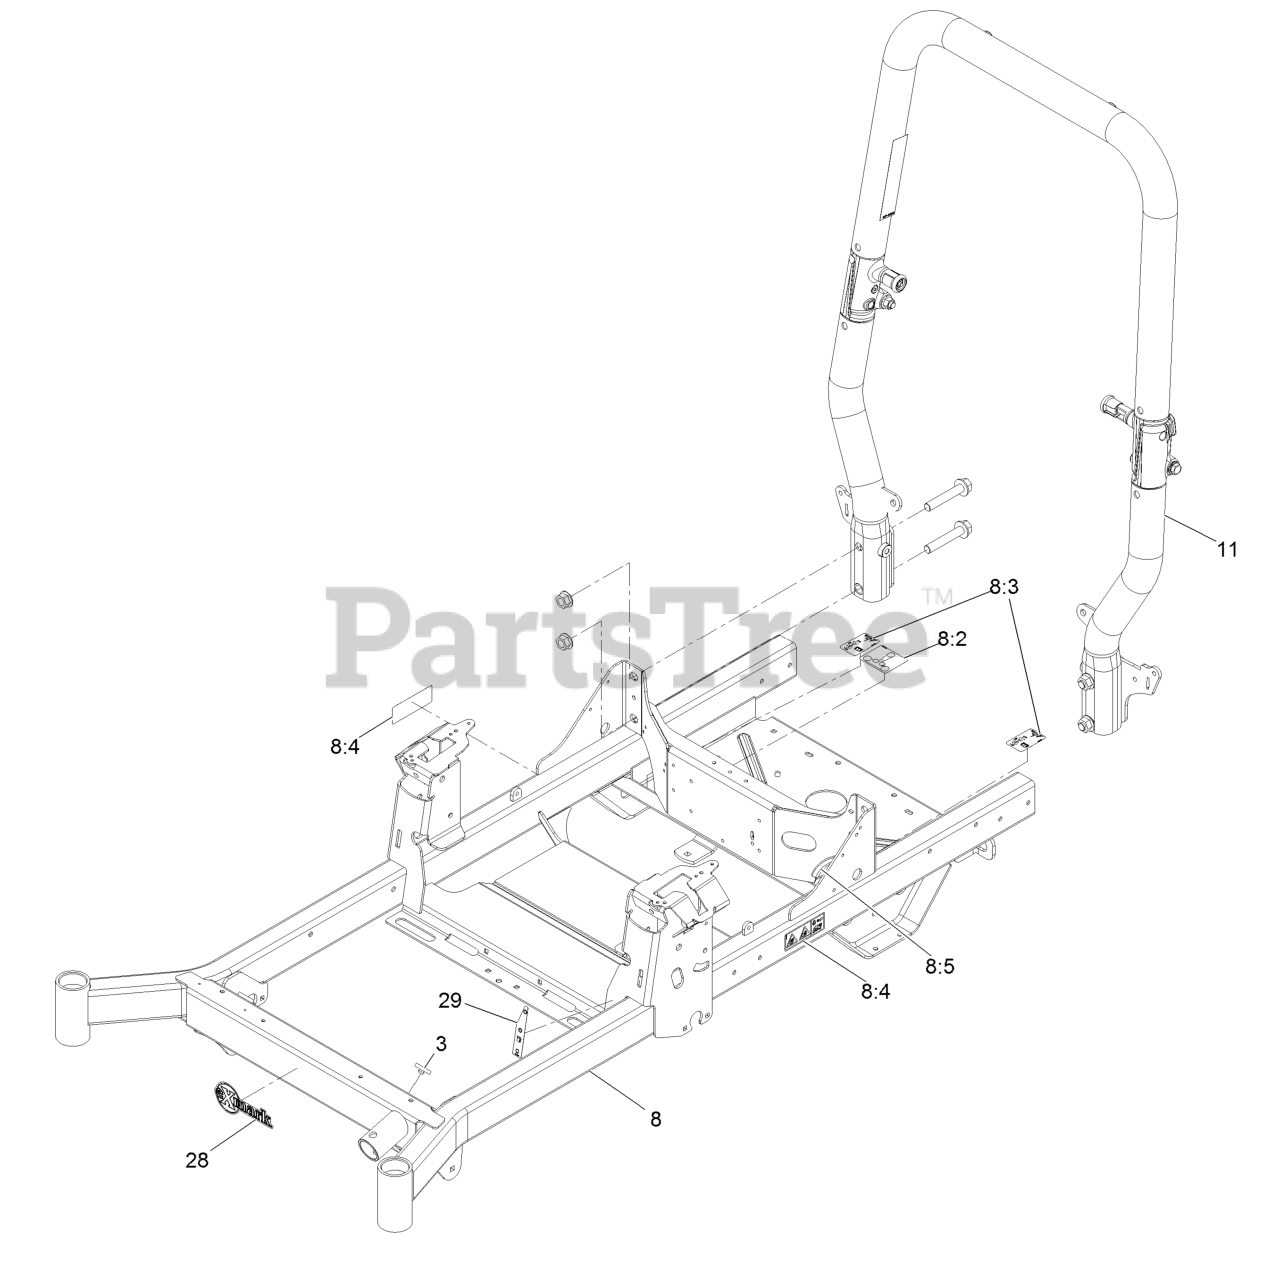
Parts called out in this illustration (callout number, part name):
3	Bumper-Push-In, Rubber
8	Suspension Frame ASM
8:2	Decal-Routing, Belt
8:3	Decal-Release, Drive
8:4	Decal-Warning
8:5	Strip-Seal
11	ASM-ROPS Tapered
28	Decal-Exmark Logo
29	Decal-Fill, Fuel
